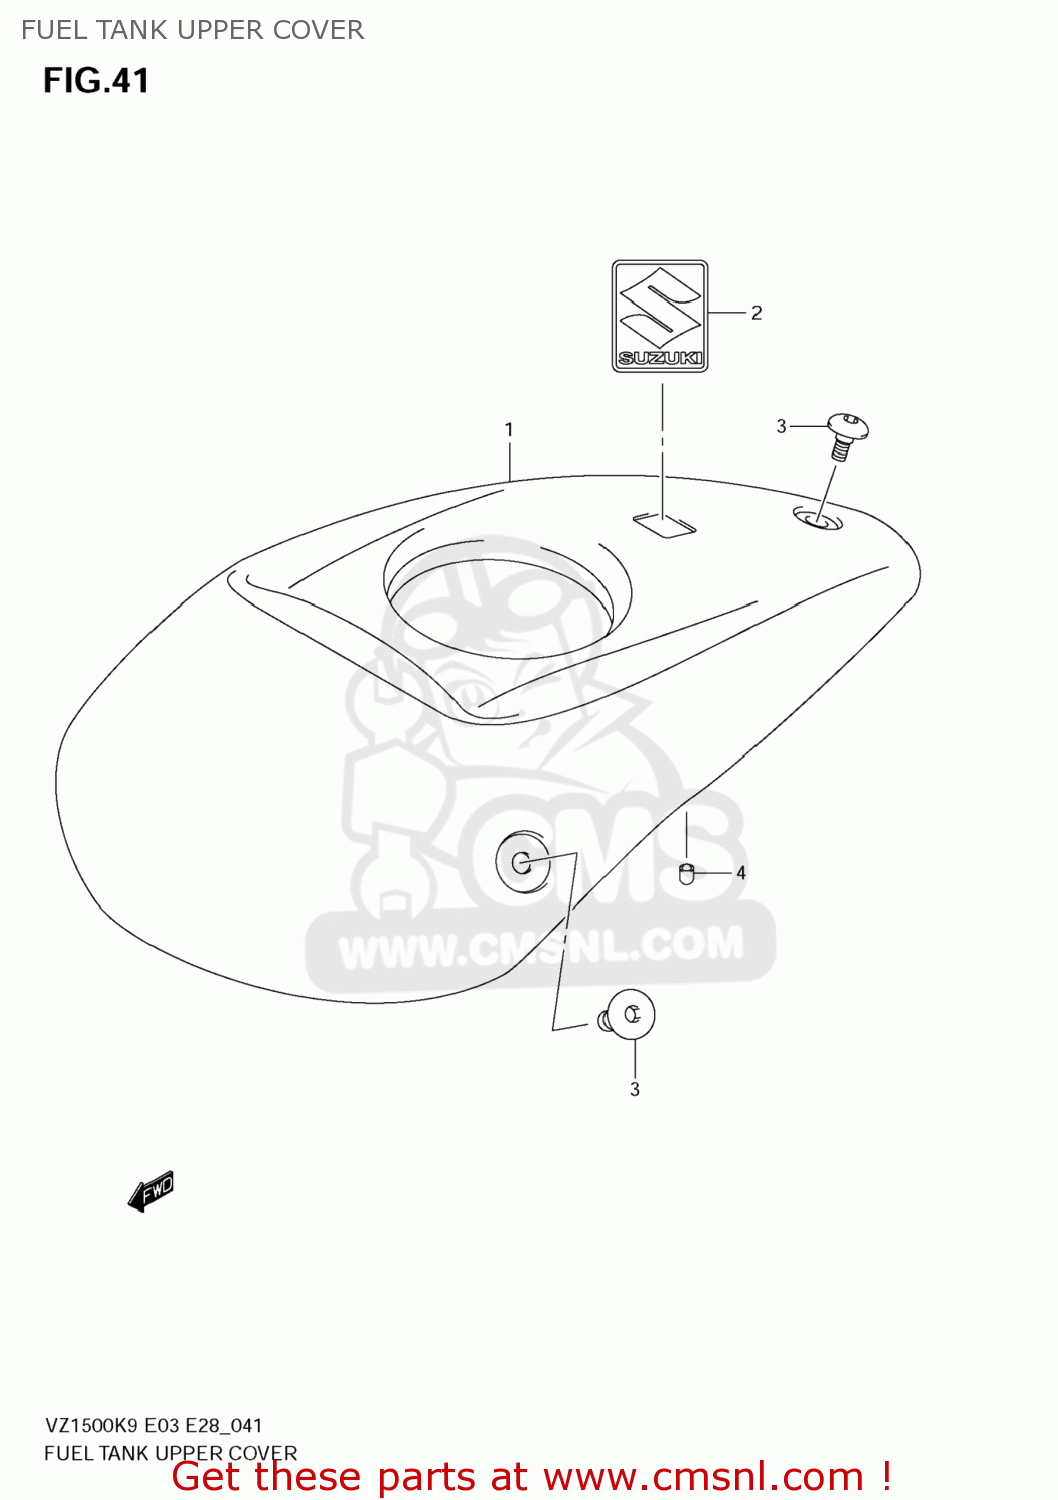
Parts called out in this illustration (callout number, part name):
1	COVER,FUEL TANK UPR
2	EMBLEM,S
3	SCREW(6X12)
4	CUSHION
